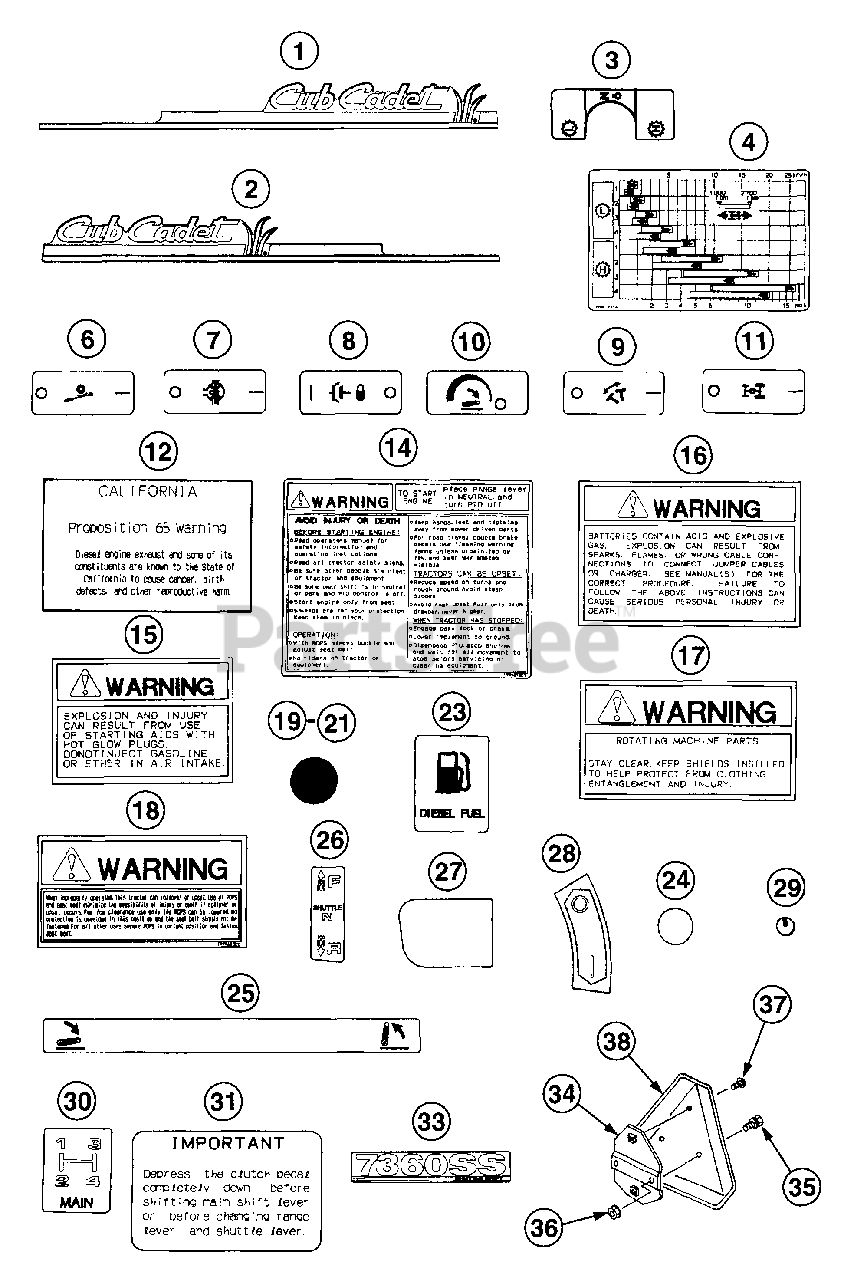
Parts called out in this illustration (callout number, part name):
1	Label, Side L.H
2	Label, Side R.H
7	Label, Diff Lock
8	Label, Declutch
10	Label, D.R. Control
12	Label, Proposition
14	Label, Warning
15	Label, Warning
16	Label, Warning
17	Label, Warning
18	Label, Warning
19	Label, Steering
25	Label, Position
26	Label, Shuttle
28	Label, Side Cover
30	Label, main Change
38	Smv Emblem
